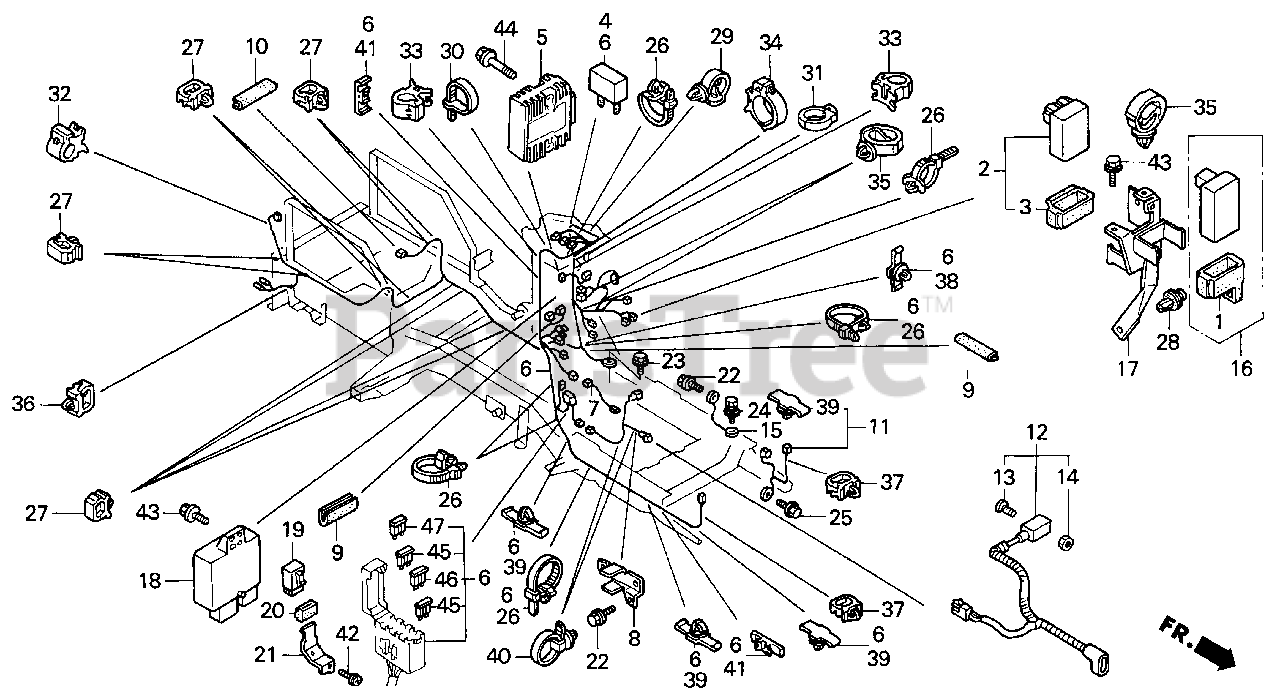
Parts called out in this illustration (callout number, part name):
1	RUBBER, IGNITION CONTROL MODULE
2	MODULE, IGNITION CONTROL (CDI)
3	CUSHION, IGNITION CONTROL MODULE
4	RECTIFIER ASSY., SILICON (STANLEY)
5	RECTIFIER ASSY., REGULATOR (10A)
6	WIRE HARNESS ASSY., MAIN
7	WIRE HARNESS ASSY., ENGINE
8	BRACKET, WIRE HARNESS
9	PROTECTOR, HARNESS
10	PROTECTOR, HARNESS
11	WIRE, RADIATOR THERMOSTAT
12	CABLE ASSY., STARTER
13	BOLT, BATTERY TERMINAL
14	NUT, BATTERY TERMINAL
15	CABLE ASSY., BONDING
16	CONTROL UNIT, ENGINE
17	BRACKET, ELECTRIC PARTS
18	RELAY ASSY., COMBINATION
19	RELAY, STARTER (TATEISHI)
20	SUSPENSION, STARTER RELAY (TATEISHI)
21	BRACKET, STARTER RELAY
22	BOLT, FLANGE (6X12) (CT200)
23	BOLT, GROUND (6X16) (SN)
24	BOLT, GROUND (8X20) (ZN)
25	BOLT, GROUND (6X12) (SN)
26	BAND, WIRE HARNESS (WHITE)
27	CLIP, HARNESS (15MM) (BLUE)
28	CLIP, RR. DUCT
29	CLIP, WIRE HARNESS
30	BAND, WIRE
31	CLIP, WIRE HARNESS
32	CLIP, CABLE (8MM)
33	CLIP, CABLE (20MM)
34	CLIP, CABLE (25MM)
35	CLIP, HARNESS
36	CLIP, WIRE HARNESS
37	CLIP, HARNESS (7MM)
38	CLIP, WIRE HARNESS (BLACK)(HARNESS TAPING)
39	CLIP, WIRE HARNESS (50MM) (GRAY)
40	BAND, WIRE HARNESS (123.5MM) (BLUE)
41	CLIP, WIRE HARNESS (BLACK)
42	SCREW-WASHER (6X12)
43	BOLT, FLANGE (6X12)
44	BOLT, FLANGE (6X20)
45	FUSE, BLADE (5A)
46	FUSE, BLADE (7.5A)
47	FUSE, BLADE (20A)
